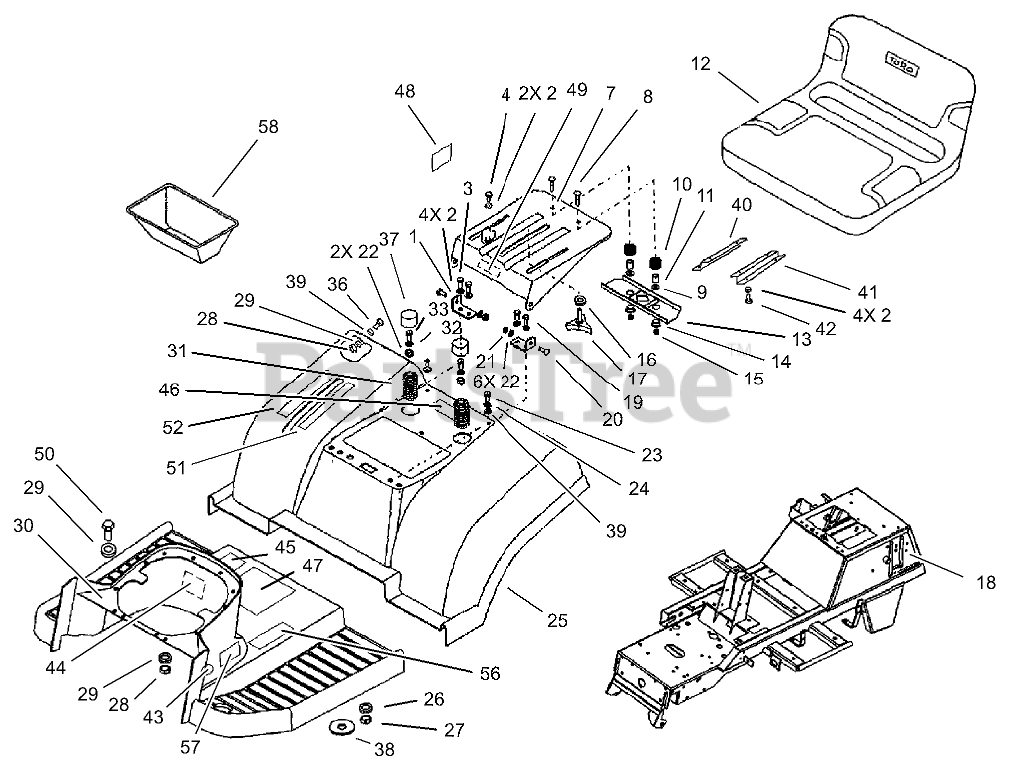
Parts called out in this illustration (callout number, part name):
1	BRACKET-SUPPORT, SEAT
2	WASHER-LOCK, SPRING
3	SCREW-HH
4	BOLT-HEX
7	SUPPORT-SEAT
8	BOLT-CARRIAGE
9	WASHER-FLAT
10	SPRING-SEAT
11	SPACER-SPLIT
12	SEAT
13	BRACKET
14	BUSHING
15	NUT-LOCK
16	WASHER-SPRING
17	KNOB-ADJUSTMENT
18	FRAME-CHASSIS
19	SCREW-HH
20	SCREW-SUPPORT, SEAT
21	WASHER-PLAIN
22	NUT-LOCK, NI
23	SCREW-HSFH
24	WASHER-FINISH
25	Fender
26	WASHER-FLAT
27	NUT-LOCK, NI
28	NUT-LOCK
29	WASHER-FLAT
30	FOOTREST ASM
31	SPRING-SEAT
32	WASHER-PLAIN
33	SCREW-HH
36	BOLT-CARRIAGE
37	CAP-HUB
38	WASHER-RUBBER
39	WASHER-RUBBER
40	BRACKET-RIGHT SEAT
41	BRACKET-LEFT SEAT
42	Screw
43	DECAL-BRAKE, PARKING
44	DECAL-STARTING
45	DECAL-OPERATION, HYDRO
46	DECAL-BAG TO FRAME
47	DECAL-INSTRUCTION
48	DECAL-SWITCH
49	DECAL-DANGER
50	SCREW-HH
51	DECAL-HOC, LH
52	DECAL-HOC, RH
56	DECAL-OPERATION
57	DECAL-TOWER
58	Box-Battery
